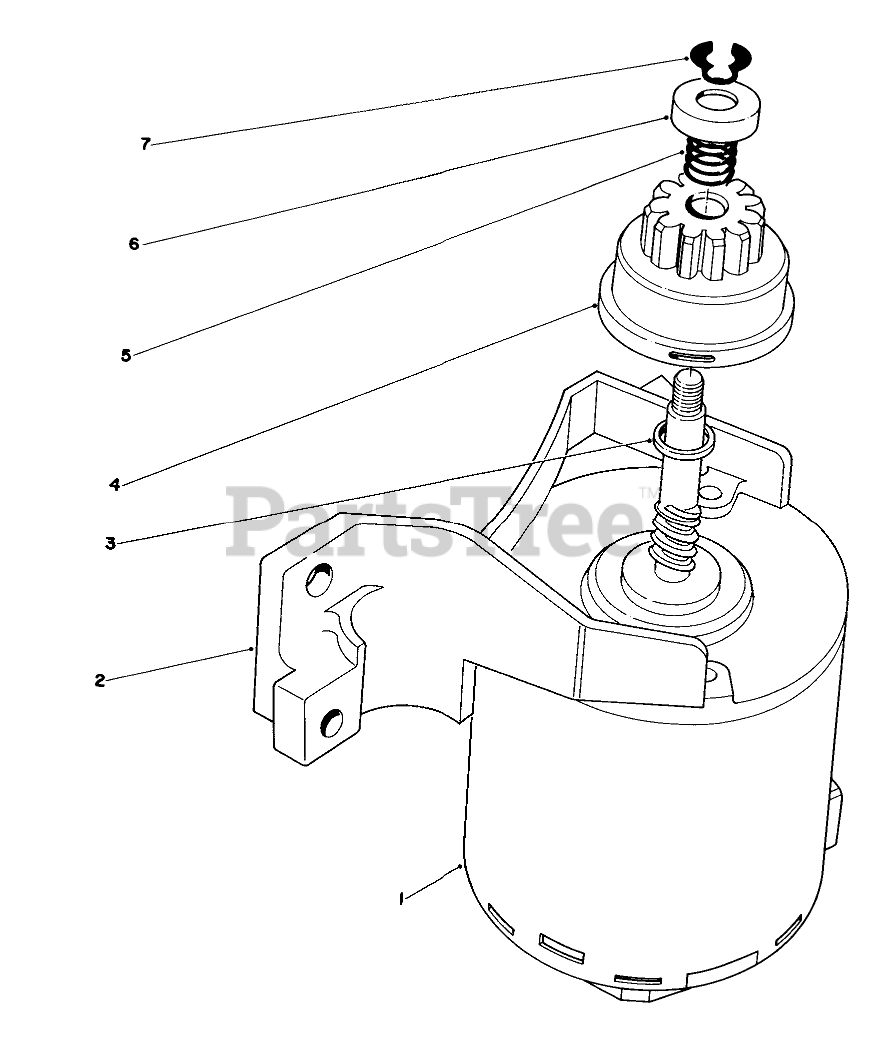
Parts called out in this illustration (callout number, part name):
1	End Plate W/Bushing
2	BRKT END FRAME
3	SPACER
4	PINION ASM
5	COMPRESSION SPRING
6	PINION STOP
7	RING-RETAINING
